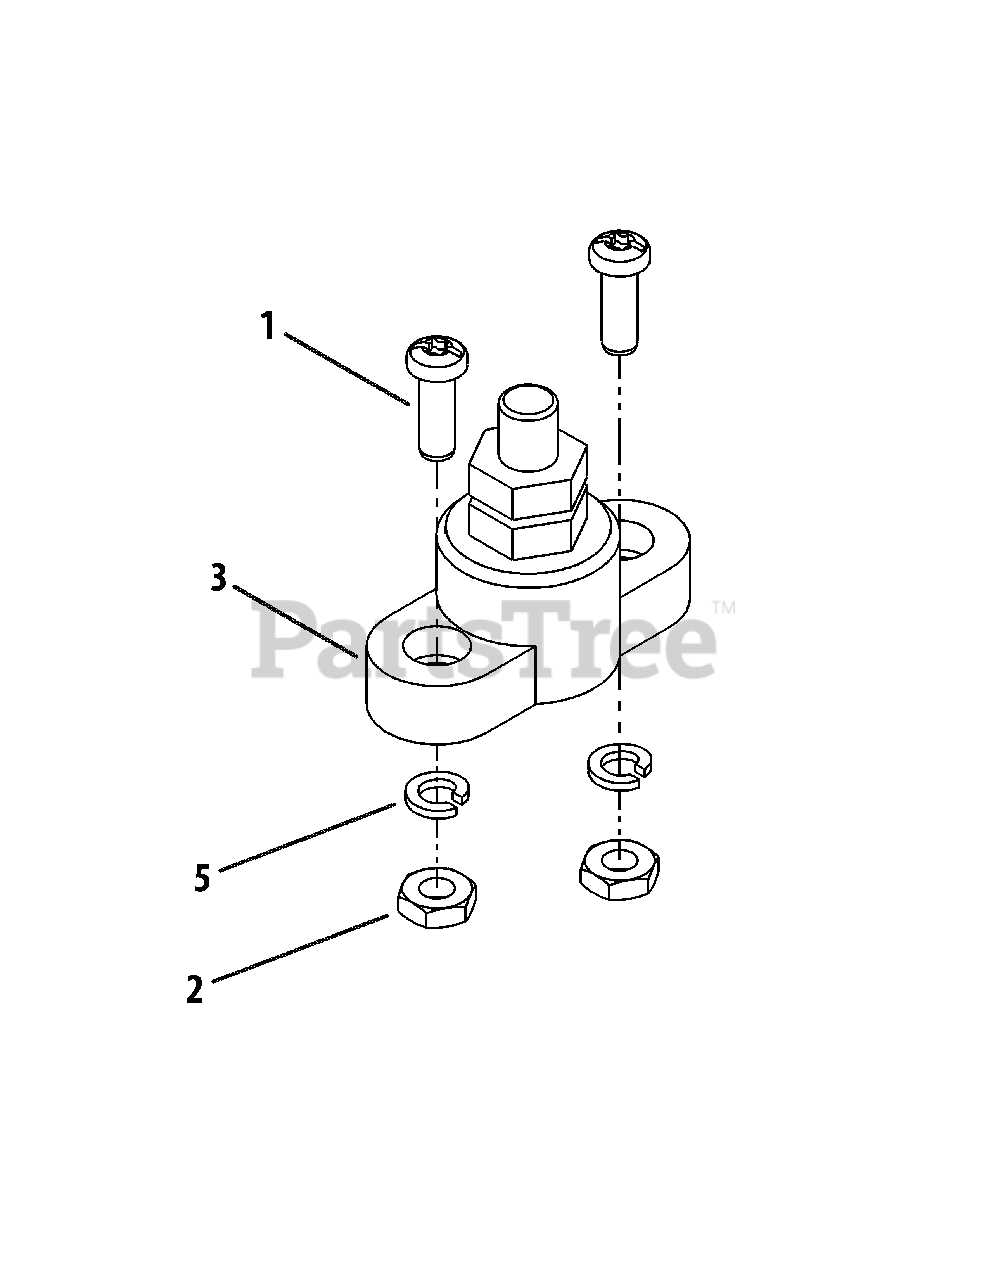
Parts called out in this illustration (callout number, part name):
1	Screw
2	Hex Nut, #10-32
3	Electric Power Distribution Post
5	Lock Washer, #10 Regular Duty
